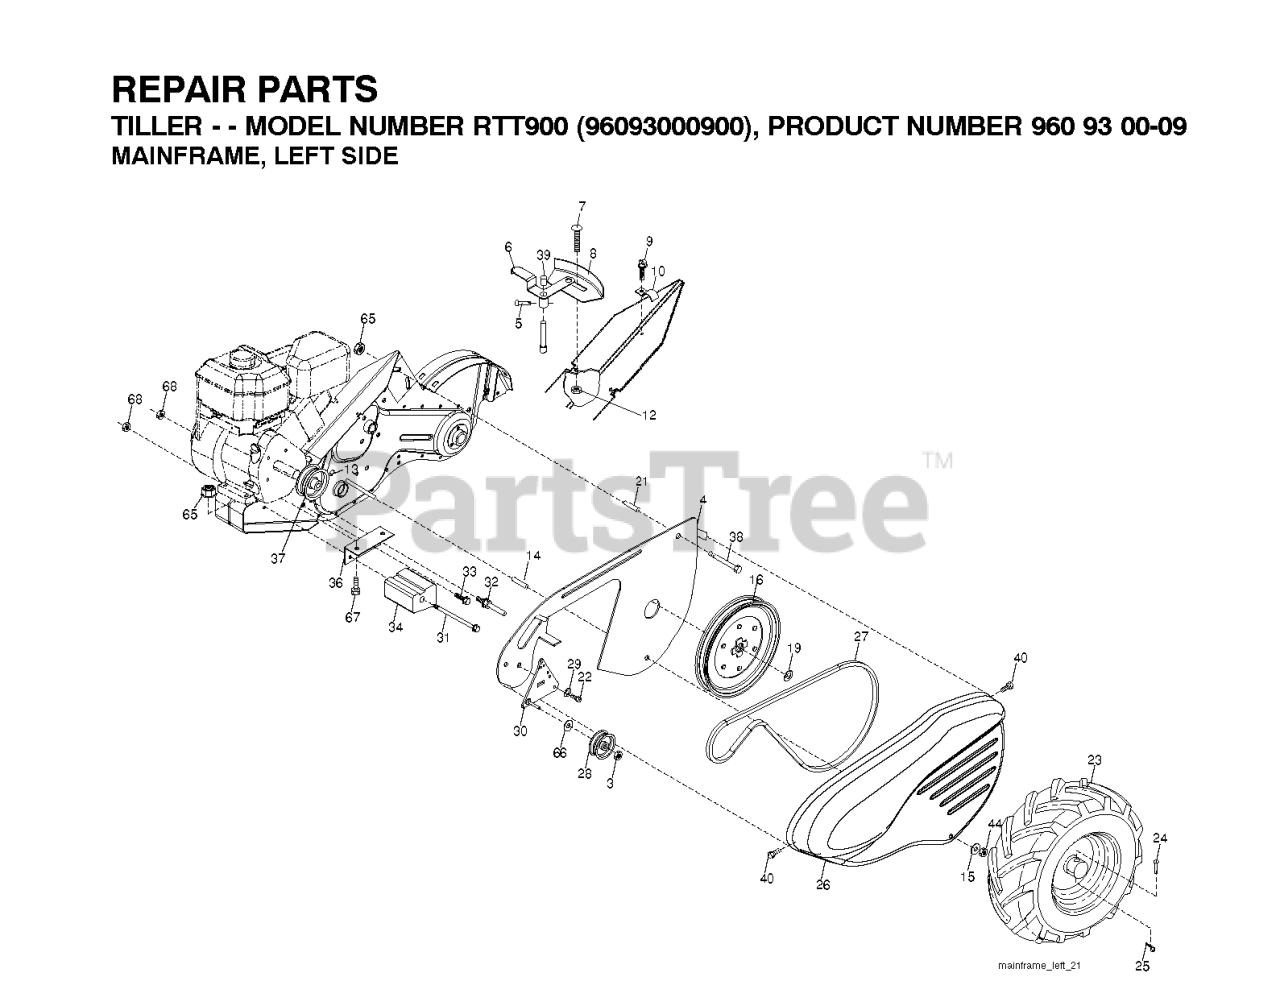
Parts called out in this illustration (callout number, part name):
3	NUT.HEX.3/8-16UNC
4	SHIELD
5	PIN.SPIROL.FLARED
6	LEVER ASM CRT
8	PANEL.INDICATOR.SHIFT.BLACK
9	TAPPING SCREW
10	CONDUIT.CLIP.PLATED
12	NUT
14	SPACER CRT
15	WASHER
16	SHEAVE, TRANSMISSION
19	RETAINING RING LT
21	SPACER-SPLIT.327 X .42
23	RIM.ASM.6".SILVER
23	TIRE.13X5-6.CHEVRON.TILLER
23	VALVE STEM LT
24	RIVET,DRILLED
25	RETAINER M
26	RP BELT GUARD
27	V-BELT
28	PULLEY-IDLER TI
30	BRACKET.ASM.IDLER.BLACK
32	SHIFT ARM CRT
33	BOLT
34	COUNTERWEIGHT, RH
36	BRACKET LH CRT
37	RP.ENGINE PULLEY
38	BOLT
39	CAP.PLUNGER.BLACK
40	SCREW.HEX.WSH.SLT.#10-24X.50
44	NUT.71038.31-18.HEX.NYLOCK
65	LOCKNUT-FLANGE 5/16-18
66	WASHER
67	BOLT
